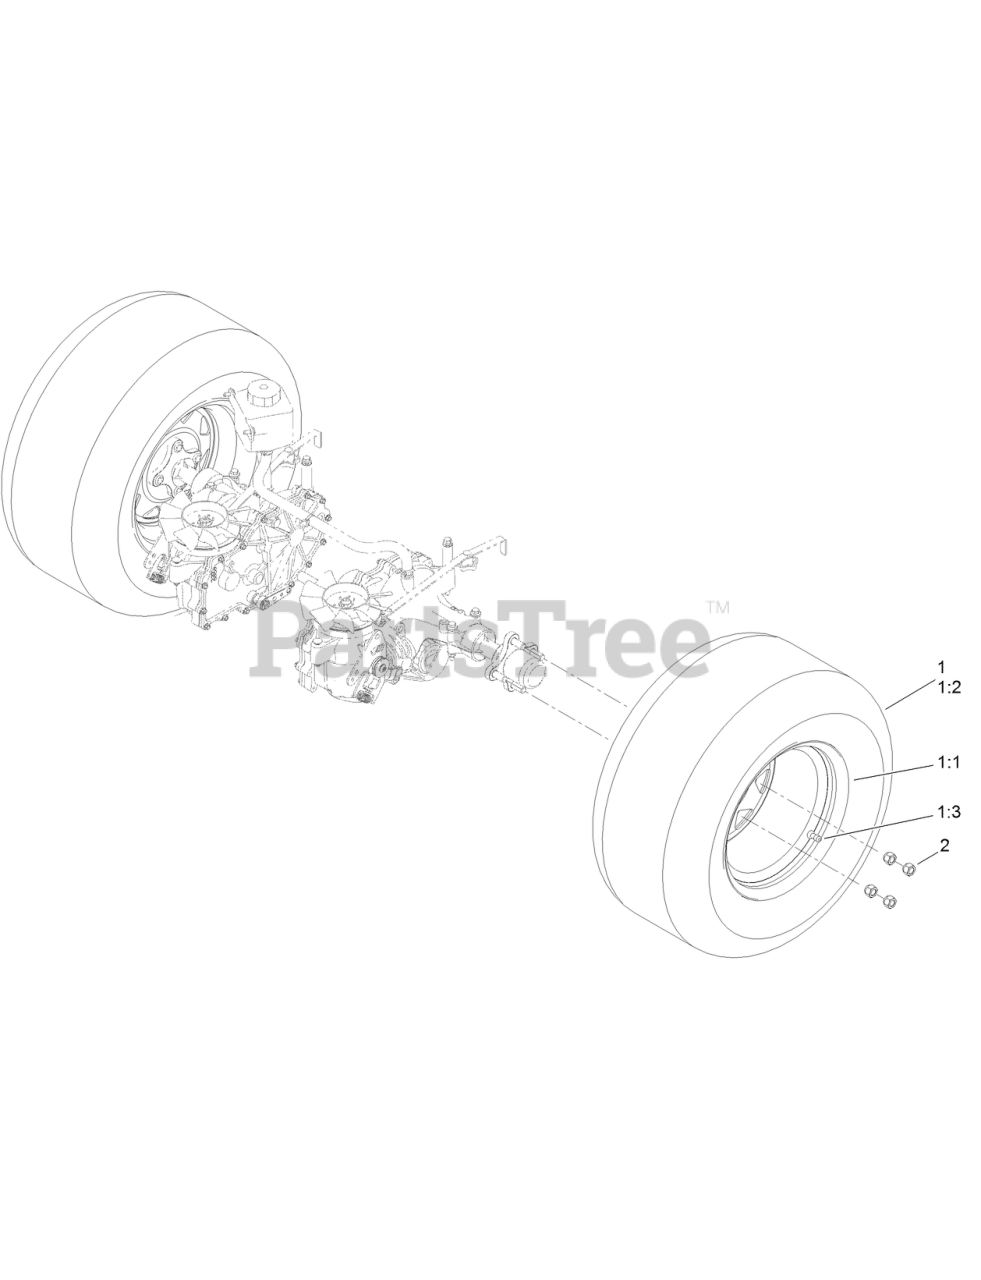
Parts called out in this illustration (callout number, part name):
1	WHEEL AND TIRE ASM
1:2	TIRE-DRIVE
2	NUT-LUG
